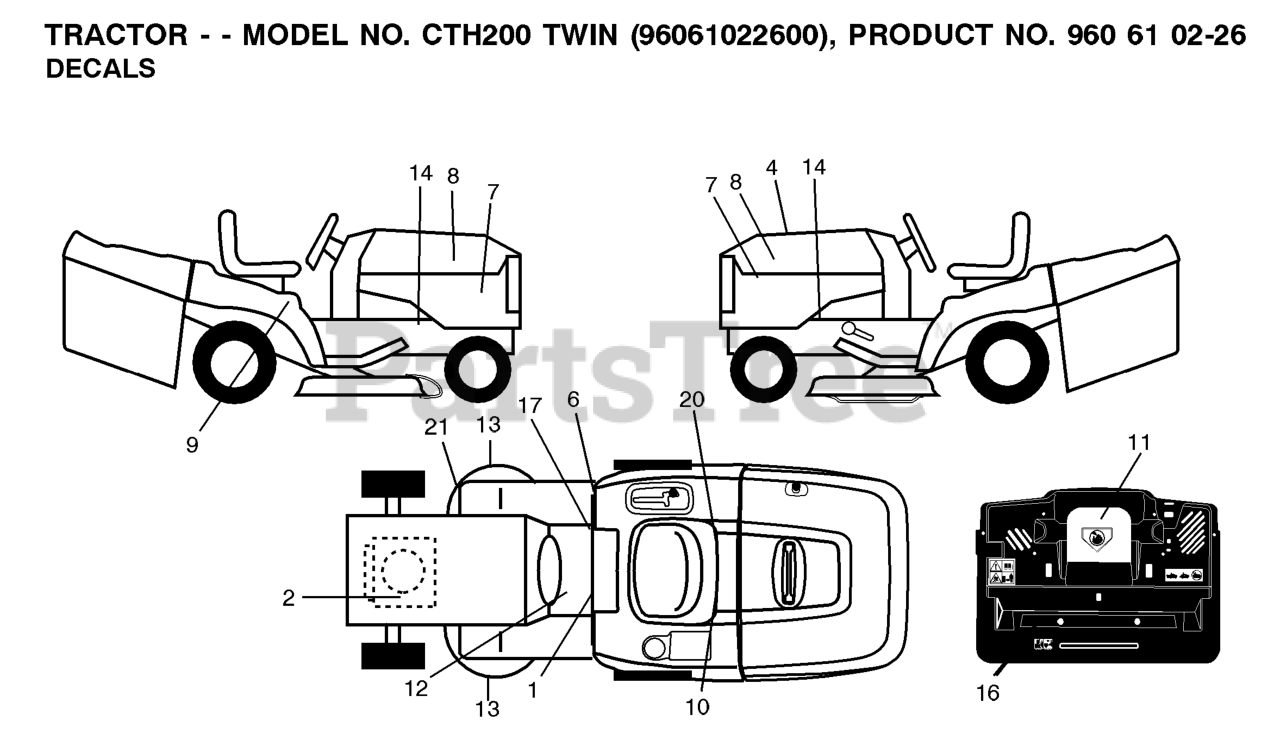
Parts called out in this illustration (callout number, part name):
1	LABEL
2	DECAL
6	Decal, Fender 100 DB/CE
8	DECAL.HOOD.NAMELOGO.HUSQ
9	Decal, Fender 100 DB/CE
10	DECAL BTRY SYMBOLS
11	DECAL.INTERNATIONL.CUTFINGER
12	DECAL
16	DECAL
17	DECAL PARK BRAKE
20	DECAL.BYPASS.FENDER.CRD.LT.YT
